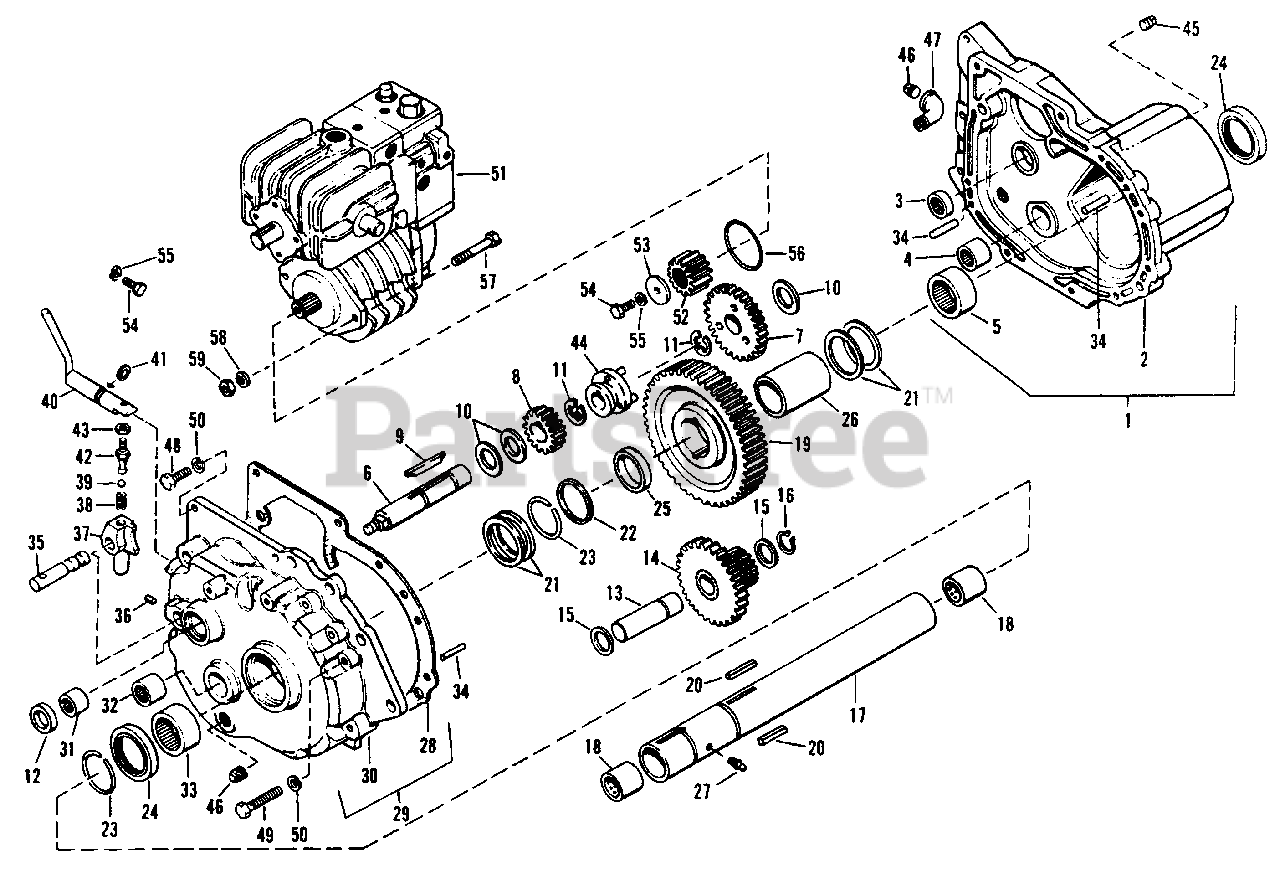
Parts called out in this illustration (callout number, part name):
1	Gear Case Complete (Incl. 2-5)
2	Gear Case
3	Needle Bearing
4	Needle Bearing
5	Needle Bearing
6	Brake Shaft
7	Gear - 1st Interm.
8	Sliding Pinion
11	Retainer Ring
13	Shaft, Interm.
14	Pinion & Gear Assembly
16	Retaining Ring
17	Axle Tube Assembly
19	Drive Gear
25	Spacer (R.H. Side)
26	Spacer (L.H. Side)
27	Grease Fitting
28	Gear Case Gasket
29	Gear Case Cover Sub. Assy., (Includes 30-33)
30	Gear Case Cover
31	Needle Bearing
32	Needle Bearing
33	Needle Bearing
34	Roll Pin, 3/8" x 1"
35	Shifter Shaft
36	Set Screw, 5/16"-18 x 1/2"
37	Shift Fork
39	Shift Lock Ball
40	Shift Shaft Assembly
43	Hex Jam Nut, 5/16"-24
44	Drive Flange Assembly
45	Pipe Plug, 1/4"
46	Pipe Plug, 3/8"
47	Street Elbow, 3/8"
48	Hex Capscrew, 5/16"-18 x 1"
49	Hex Capscrew, 5/16"-18 x 2"
50	Lockwasher, 5/16"
51	Hydrostatic Pump & Motor Unit
52	Motor Shaft Pinion
54	Hex Capscrew, 5/16"-24 x 3/4"
55	Lockwasher, 5/16"
57	Hex Capscrew, 7/16"-14 x 4"
58	Lockwasher, 7/16"
59	Full Hex Nut, 7/16"-14
